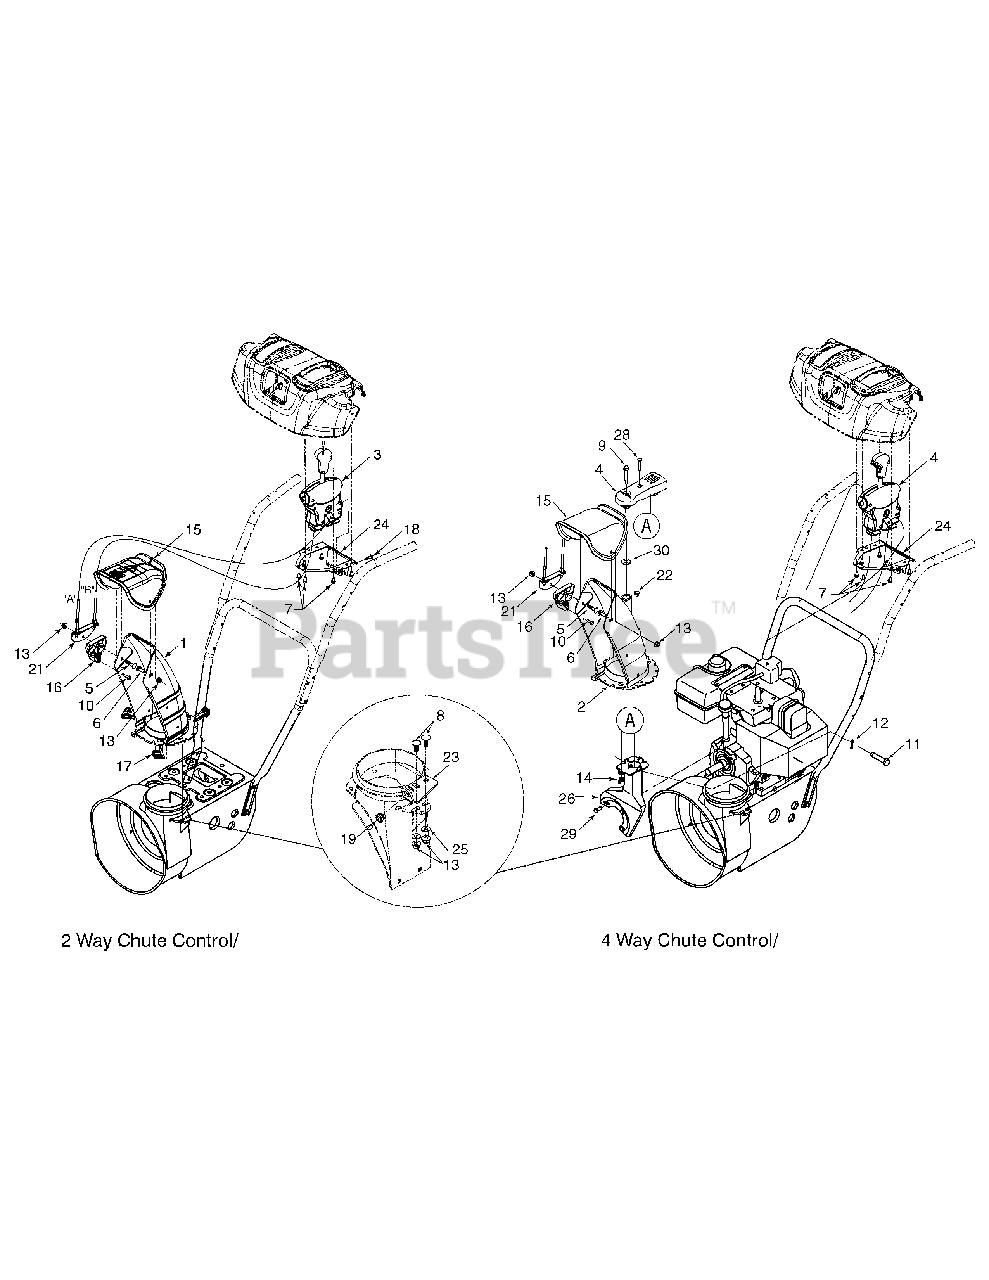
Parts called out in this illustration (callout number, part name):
1	Lower Chute (2 Way)
2	Lower Chute (4 Way)
3	2 Way Chute Control Assembly
4	4 Way Chute Control Assembly Service Kit
5	Carriage Bolt 5/16-18 x 1.50 Gr. 2
6	Carriage Screw 5/16-18 x 1.0
7	Hi-Lo Screw 1/4-15 x .5
8	Carriage Bolt 5/16-18 x .75" Lg
9	Shoulder Screw .312 x 1.7:1/4-20
10	Hex Tapp Scr 1/4 x .75" Lg.
11	Clevis Pin 3/8 x 1.87
12	Bow Tie Cotter Pin
13	Flange Locknut 5/16-18 Gr. F Nylon
14	Wing Nut 1/4-20
15	Upper Chute w/Export Label, Remote
16	Cable Guide
17	Chute Flange Keeper
18	Shoulder Screw .25 x .50:10-24
19	Plastic Bushing .380 ID
22	Hex L-Flanged Nut 1/4-20 Gr. F Nylon
25	Flat Washer .349 ID x .879 OD x .063
26	Support Bracket
27	Hi-Lo Screw 1/4-15 x .50
28	Hex Hd. Cap Screw 1/4-20 x 1.5 Gr. 5
29	Hex Hd. Cap Screw 5/16-24 x .75
30	Flat Washer .25 ID x .63 OD x .0515
